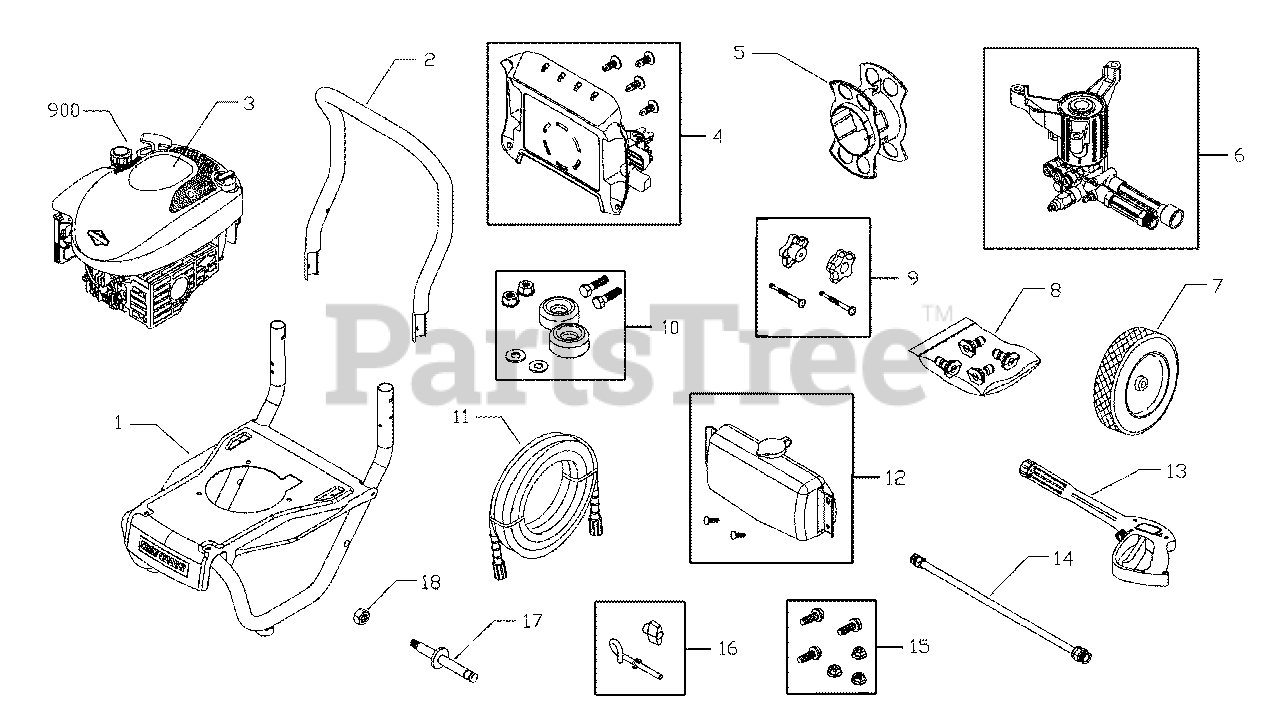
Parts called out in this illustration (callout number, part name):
2	HANDLE (POIGNÉE)
3	DECAL (DÉCALQUE)
4	BILLBOARD (PANNEAU D’AFFICHAGE)
5	WRAP-HOSE (DÉVIDOIR-BOYAU)
6	PUMP (POMPE)
8	KIT-QC NOZZLES (ENSEMBLE-BUSES RACCORDS RAPIDES)
9	KIT-HARDWARE HANDLE (ENSEMBLE-QUINCAILLERIE DE POIGNÉE)
10	MOUNT-VIBRATION (MONTANT-ANTIVIBRATILE)
11	HOSE (BOYAU)
12	TANK-CHEMICAL (RÉSERVOIR-PRODUITS CHIMIQUES)
13	GUN (PISTOLET)
14	EXTENSION-QC (RALLONGE-RACCORDS RAPIDES)
15	KIT-HARDWARE, PUMP MOUNTING (ENSEMBLE-QUINCAILLERIE, MONTAGE DE POMPE)
16	GUIDE-ROPE (GUIDE-CÂBLE)
17	AXLE (AXE)
18	NUT (ÉCROU)
